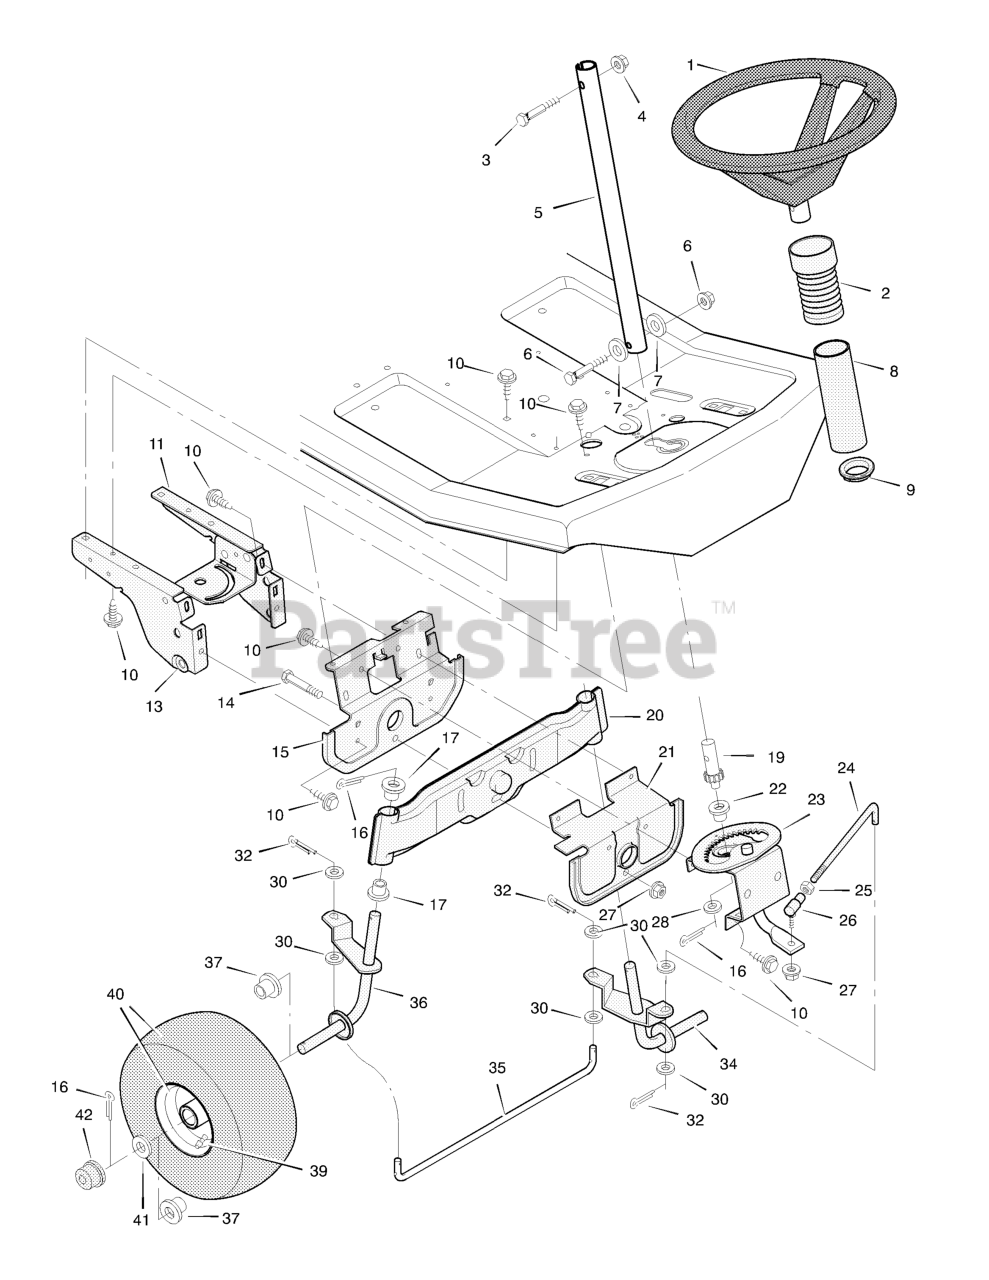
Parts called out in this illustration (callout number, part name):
1	Steering Wheels
2	Bellows
3	Bolt, Hex
4	Locknut, Flange
5	Post, Steering
6	Nut, Hex
7	Washer
8	Cover, Steering Post
9	Bearing
11	Plate, Left Suspension
13	Plate, Right Suspension
14	Bolt, Hex
15	Support, Front Axle
16	Pin, Cotter
17	Bearing, Spindle
19	Gear, Pinion
20	Axle Assembly, Front
21	Hanger Assembly, Front Axle
22	Bearing
23	Sector Assembly
24	Rod, Drag Link
25	Nut, Hex
26	Ball Joint, Steering
27	Locknut, Flange
32	Pin, Cotter
34	Spindle Assembly, Left
35	Rod, Tie
36	Spindle Assembly, Right
37	Bearing, Wheel
39	Valve Stem
40	Wheel & Tire Assembly
42	Cap, Hub
